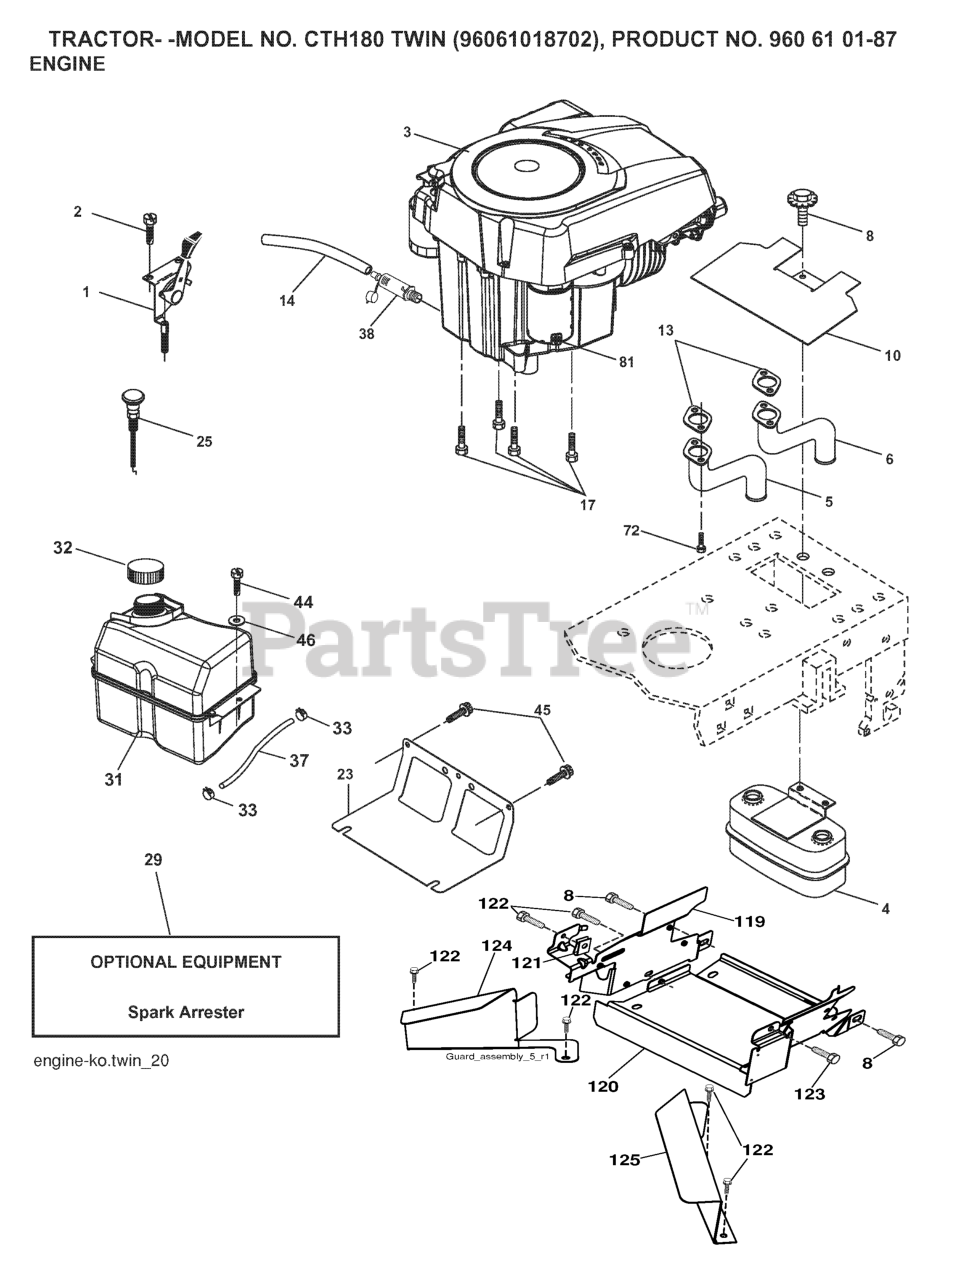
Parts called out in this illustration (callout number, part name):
1	THROTTLE CONTROL
2	SCREW
4	MUFFLER.TWIN.CYL.LOW.TONE
5	RP.PIPE-EXHAUST LH
6	RP.PIPE-EXHAUST RH
8	BOLT.5/16-18UNCX3/4 W/SEMS.BLK
10	RP SHIELD HEAT MUFFLER
14	TUBE, DRAIN OIL ASM.
17	SCREW 3/8-16X1
23	SHIELD.BROWNING.DBR.GUARD
25	CONTROL, CHOKE
29	KIT.SPARK ARRESTOR 794945 B&S
31	TANK.ASM.FUEL.FR.2.5GA.
32	FUEL CAP
33	HOSE CLAMP
37	LINE.FUEL.20
38	PLUG DRAIN OIL EASY
44	SCREW HEXWSHR 1/4-20X3/4
45	SCREW, 3/8-16X3/4
72	SCREW.SOCKET HD.5/16-1
81	NUT
119	LENKRAD
120	GUARD 532199767
122	SCREW.1/4-20X5/8
123	SCREW, 5/16-18 X 1/2
